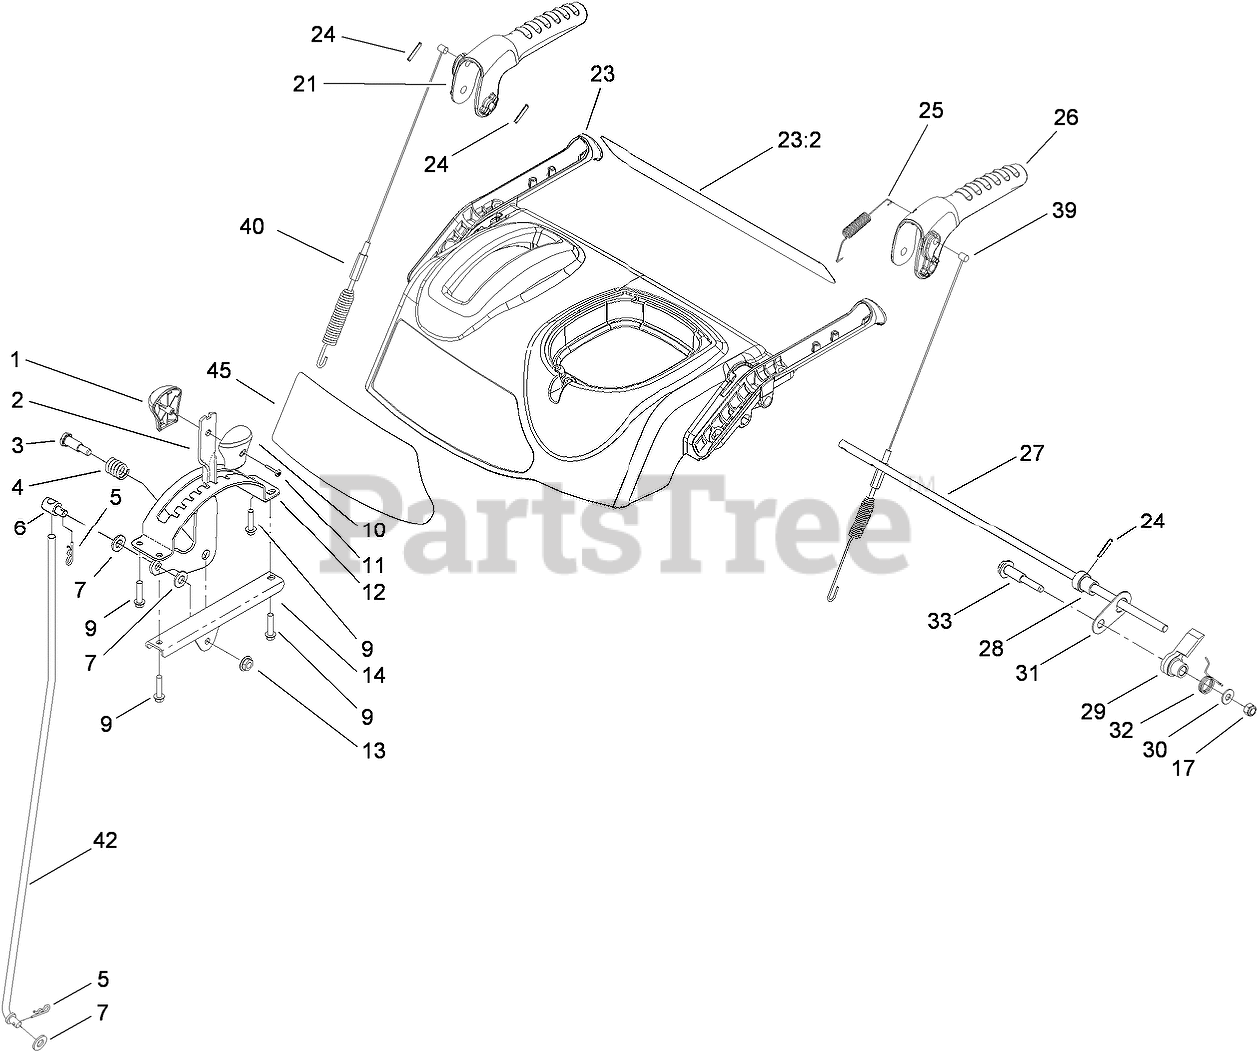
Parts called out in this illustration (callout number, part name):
1	KNOB-SHIFT, RH
2	SELECTOR-SPEED
3	SCREW-SHOULDER
4	SPRING-COMPRESSION
5	PIN-COTTER
6	TRUNNION-ROD
7	WASHER-FLAT
9	SCREW-PLASTITE
10	KNOB-SHIFT, LH
11	SCREW-PPH
12	GUIDE-SELECTOR, SPEED
13	NUT-HF
14	MOUNT-SELECTOR, SPEED
17	NUT-LOCK, NI
21	LEVER-AUGER
23	CONTROL PANEL ASM
23:2	DECAL-PANEL, CONTROL
24	PIN-SPRING
25	SPRING-TENSION
26	LEVER-TRACTION
27	ROD-LOCKOUT
28	CAM-LOCKOUT
29	LATCH-LOCKOUT
30	WASHER-FLAT
31	LINK-LOCKOUT
32	SPRING-TORSION
33	SCREW-SHOULDER
39	CABLE-TRACTION
40	CABLE-AUGER
42	ROD-SHIFT
45	DECAL-CONTROL PANEL
